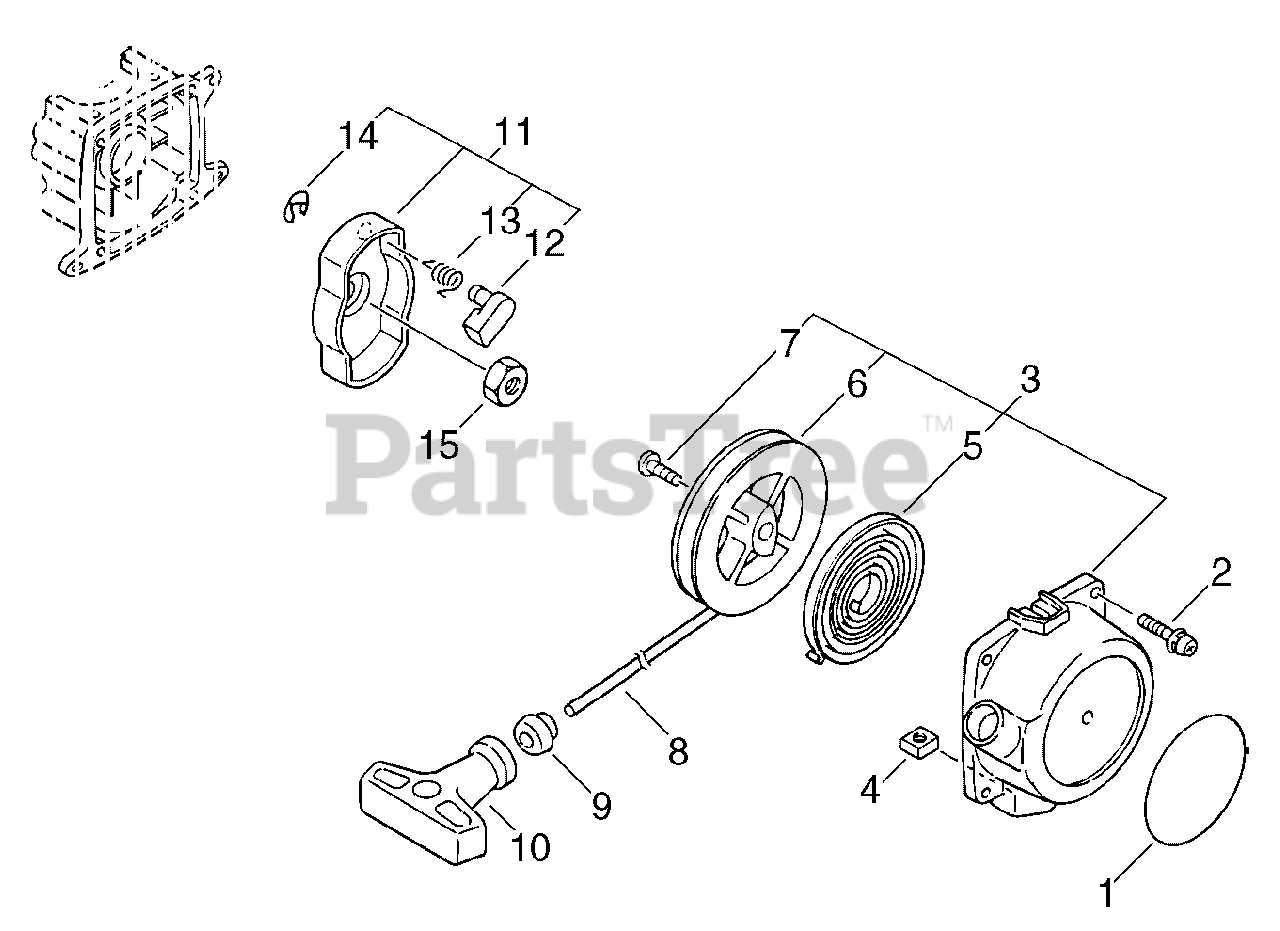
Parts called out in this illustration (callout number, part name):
1	LABEL, ECHO
2	BOLT 4×14
3	STARTER ASSY, RECOIL
4	NUT M5
5	SPRING, RECOIL
6	REEL, ROPE
7	SCREW
8	ROPE, STARTER 3×800
9	GUIDE, ROPE
10	GRIP, STARTER
11	PAWL ASSY, STARTER
12	PAWL, STARTER
13	SPRING, RETURN
14	E-RING 4
15	NUT 8×1.25
